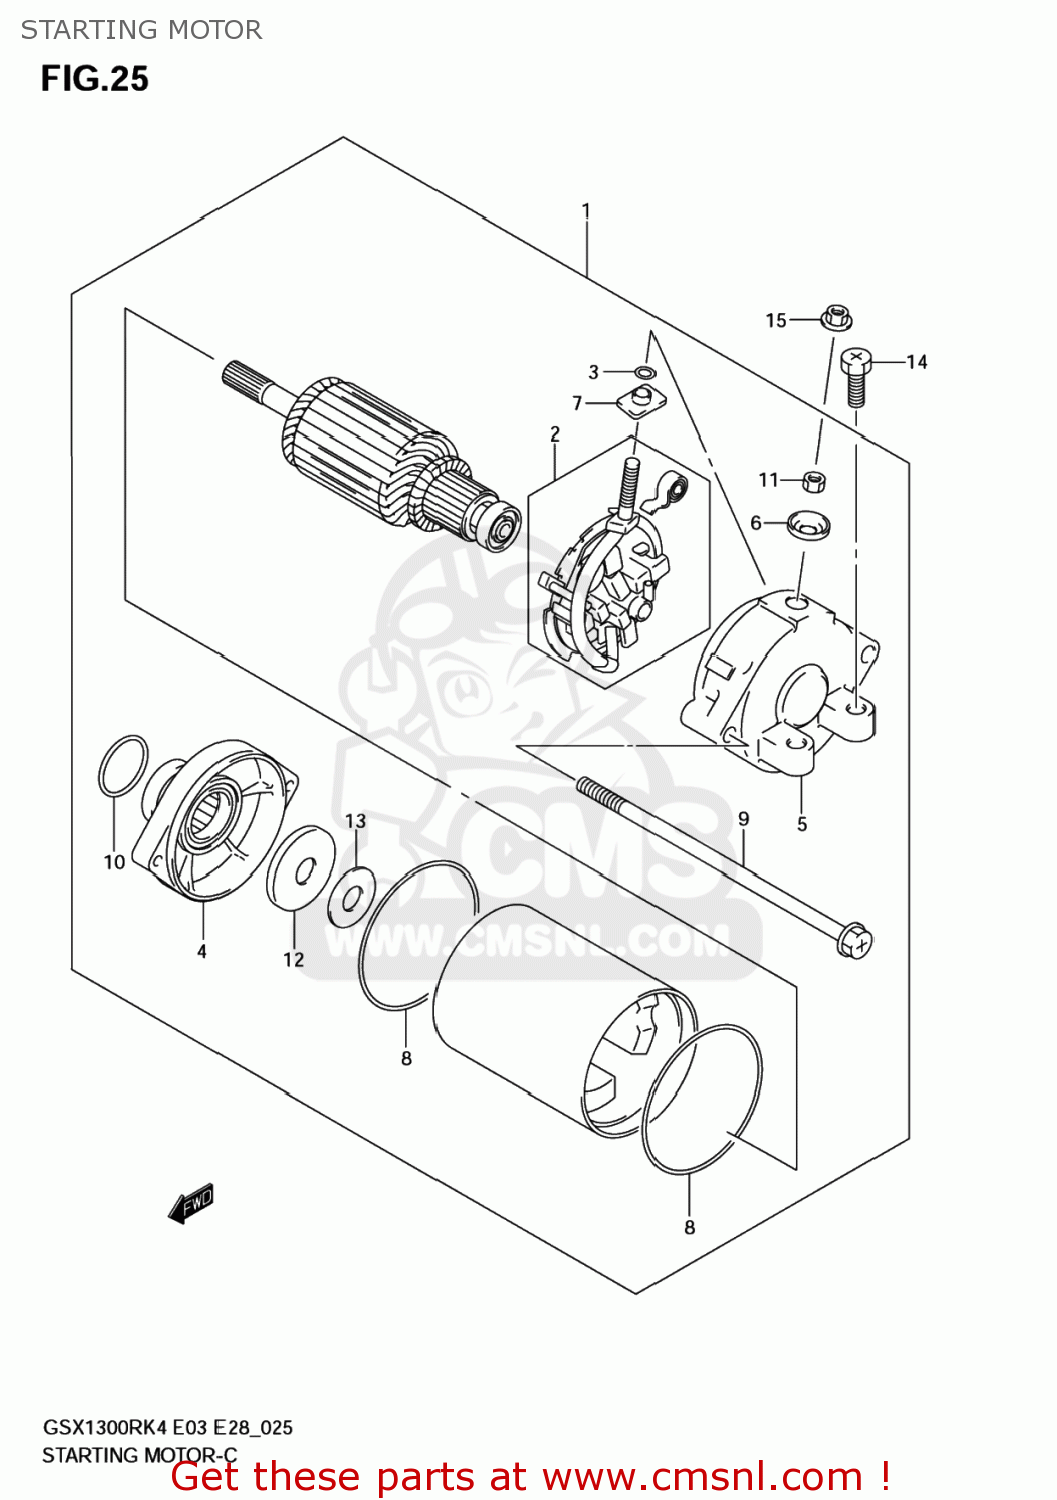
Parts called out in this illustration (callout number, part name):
1	MOTOR ASSY,STARTING
2	HOLDER SET,BRUSH
3	O RING
4	HOUSING ASSY,STARTER
5	FRAME,STARTER END
6	BUSHING
7	BUSHING
8	O RING
9	BOLT
10	O RING(D:3,ID:24.5)
11	NUT
12	WASHER
13	SHIM
14	SCREW (6X25)
15	NUT
